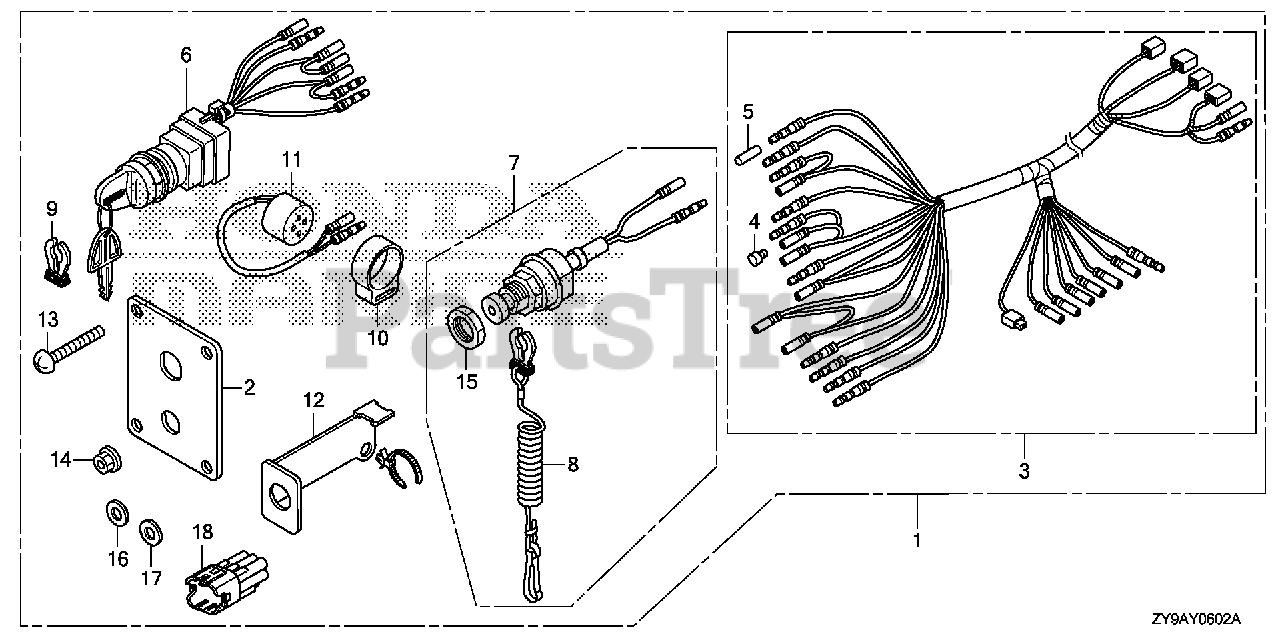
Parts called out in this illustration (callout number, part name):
1	PANEL KIT, SWITCH (SINGLE)
2	PANEL, CONTROL (SINGLE)
3	HARNESS ASSY., SWITCH PANEL
4	PLUG, CONNECTOR (INNER) (TROLLING CONTROL)
5	PLUG, CONNECTOR (OUTER) (ENGINE NO.)
6	SWITCH ASSY., COMBINATION
7	SWITCH ASSY., EMERGENCY STOP (SINGLE)
8	WIRE, EMERGENCY
9	CLIP, EMERGENCY LOCK
10	SUSPENSION, AUDIBLE PILOT
11	BUZZER, WARNING
12	BRACKET
13	SCREW, PAN (5X40) DUAL QTY = (8) (SINGLE)
14	NUT, FLANGE (5MM)
15	NUT
16	WASHER, PLAIN (5MM)
17	WASHER, SPRING (5MM)
18	DUMMY, WATERPROOF CONNECTOR (GREEN)
